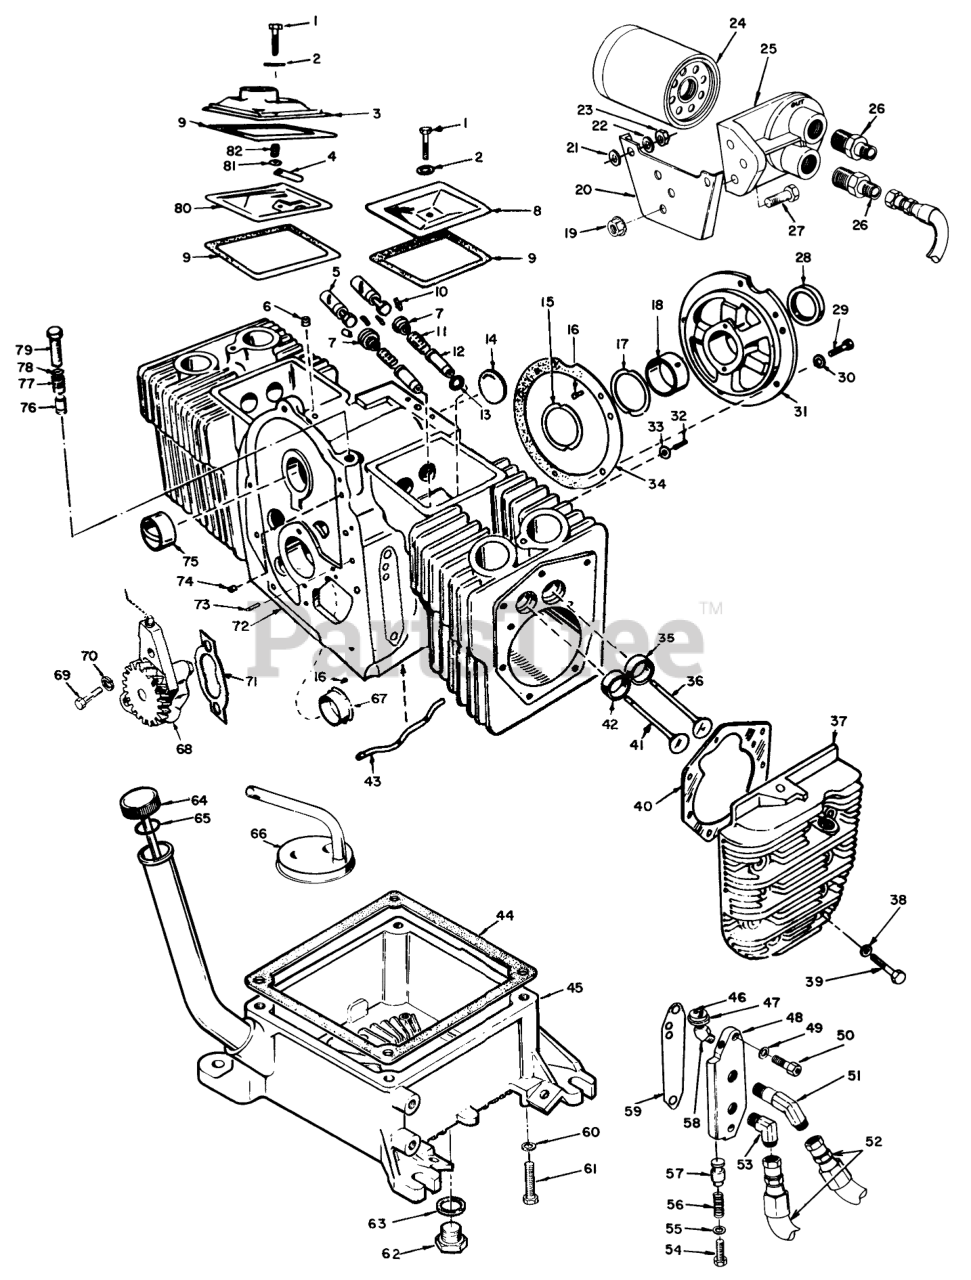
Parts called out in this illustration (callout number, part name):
1	Screw-Cap Hex Hd.
2	Washer, Flat-Copper
3	Cover-Valve
4	Reed-Breather Valve
5	Tappet, Valve (Standard)
6	Plug, Breather Hole
7	HYD MOTOR ASM
8	RH LEVER / GRIP ASM
9	Gasket, Valve Cover
10	Lock, Valve Spring
11	Spring Valve
12	Guide, Valve
13	Gasket, Intake Valve Guide
14	Plug, Welch-Camshaft Opening
15	Washer-Thrust
16	Pin, Drive-Bearing stop
17	Shim, Crankshaft End Play (.005)
18	Bearing, Crankshaft Rear Standard (Incl. Ref. #15)
19	Nut, Self-Lock
20	Bracket, Remote Oil Filter
21	Washer, Over Bracket
22	Washer, Under Bracket
23	Nut, Hex
24	Filter Oil
25	Base, Remote Oil Filter
26	Connector, Male
27	Screw Cap-Hex Hd.
28	Seal, Oil-Crankshaft Rear
29	Screw Cap-Hex Hd.
30	Washer, Lock-Spring
31	Plate, Bearing-Rear
33	Washer, Flat
34	Gasket, Bearing Plate
35	Insert, Valve Seat-Intake (Standard)
36	BRUSH-SCRAPER, WIDE (18 INCH)
37	LEVER-ACTUATING
38	Washer, Flat
39	Screw, Cap-Hex Head (Special)(5/16-18x 1-5/8")
40	SPACER
41	Valve Exhaust
42	GAS-LINE
43	Tube, Oil-Cylinder Block
44	Gasket, Oil Base
45	Base, Oil
46	Lead, Low Oil Pressure Cut Off
47	Switch, Low Oil Pressure Cut Off
48	Adapter, Oil Filter
49	Washer, Flat Copper
50	Screw, Cap-Socket Head
51	Elbow, Male (To Filter)
52	Hose, Oil
53	Elbow, Male (From Filter)
54	Screw, Cap Hex Hd.
55	Washer, Flat
56	Spring, By-Pass
57	Plunger, Bypass Valve
58	Elbow, Street 45 Deg.
59	Gasket, Oil Filter Adapter
60	Washer, Lock-Spring
61	Screw, Cap-Hex Head
62	Plug, Oil Drain
63	Gasket, Oil Drain
64	Cap and Indicator,Oil Fill
65	O-Ring, Oil Fill Cap
66	Cup, Intake-Oil Pump
67	Bearing, Crankshaft-Front(Flanged) Standard
68	Pump, Oil
69	Screw, Cap-Hex Hd.
70	Washer, Lock
71	Gasket Kit, Oil Pump
72	Block Assy. (Incl. Ref. #6 12-18,29-31, 3435, 42-43, 67,73&75
73	Pin, Gear Cover Alignment
74	Plug, Core Hole
75	Bearing, Camshaft
76	Plunger, Bypass Valve
77	Spring, By-Pass
78	Washer, Flat
79	Screw, Cap-Hex Head
80	Baffle, Breather Valve
81	Washer, Flat
82	Spring, Breather Valve
